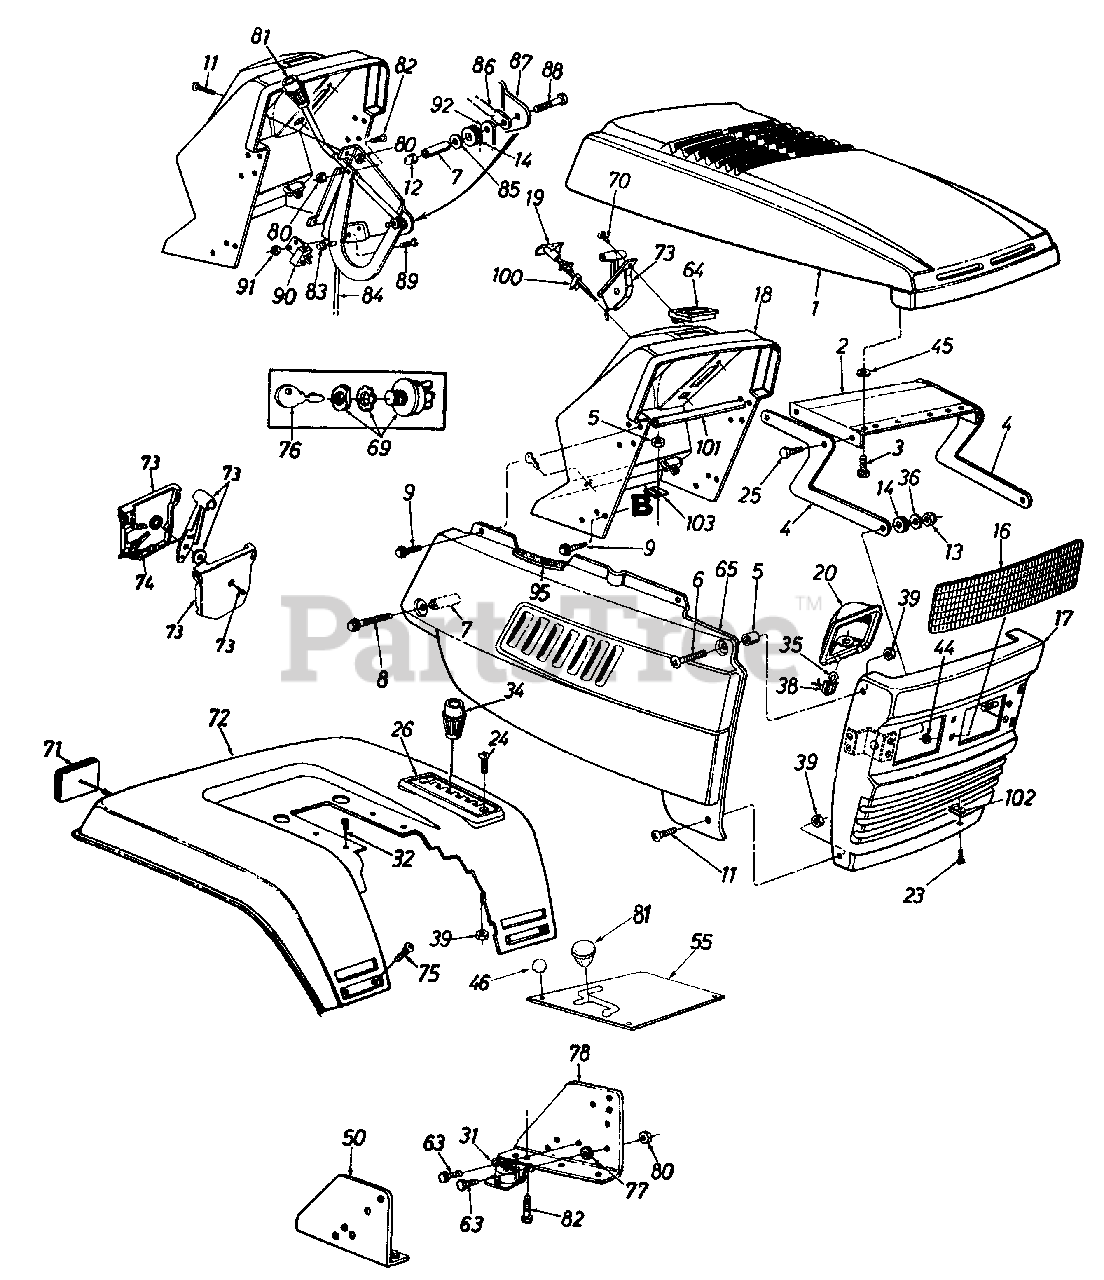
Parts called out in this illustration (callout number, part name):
1	Hood (Red)
6	Truss Hd. Mach. Scr. 1/4-20 Thd.
7	Spacer .26" I.D. x .375"
8	Hex Wash. TT-Tap Scr. 1/4-20 x 1.75" Lg
9	HexT-Tap Scr. 1/4-20 x .75" Lg.
11	Truss Mach. Scr. 1/4-20 x .5" Lg.
12	Hex Ins. L-Nut 1/4-20 Thd.
13	Hex L-Nut 5/16-18 Thd.
14	Rubber Washer
16	Headlight Lens
19	Choke Control
20	Headlight Housing
23	Hex Bolt 5/16-18 x .75" Lg.
24	Truss Mach. Scr. 1/4-20 x .75" Lg
25	Hex Wash. Hd. Scr. 1/4" x .5" Lg.
26	6-Speed Selector Plate
31	Solenoid
32	Hex Hd. Rolling Scr. 5/16-24 x .75" Lg.
34	Shift Knob
35	Lamp
36	Bell-Wash. .34" I.D. x .87"
38	Socket
39	Hex Sems Nut 1/4-20 Thd.
44	Speed Nut 5/16" I.D.
45	Fl-Wash. .406" I.D.
46	Ball Knob
64	Ammeter
70	Truss Mach. AB-Tap Scr. #10 x .5" Lg.
71	Reflector
74	Throttle Control Wire 35" Lg.
75	Carriage Bolt 1/4-20 x .5" Lg.
76	Key
77	Ext. L-Wash. 1/4" I.D.
81	Knob
82	Hex Bolt 1/4-20 x .62" Lg.
83	Push Nut
84	PTO Rod
85	Fl-Wash. .281" I.D. x .73"
86	PTO Lever
89	Truss Mach. Scr. #10-24 x .5" Lg.
90	Safety Switch
91	Hex Nut #10-24 Thd.
92	PTO Bracket
95	Trim Strip 12" Lg.
100	Retainer Clip
101	Dash Support Tube
102	U-Nut 5/16-18 Thd.
103	Dash Panel Fastening Tab
16725-0640	PANEL-SIDE RH - CO-OP GREEN (0640)
16725-0665	PANEL-SIDE RH - YARDMAN GREEN (0665)
16725-0691	PANEL-SIDE RH - BLACK JACK (0691)
17309B-0483	PANEL-SIDE-LH - CHARCOAL GRAY (0483)
17309B-0638	PANEL-SIDE-LH - MTD/TROY-BILT RED (0638)
